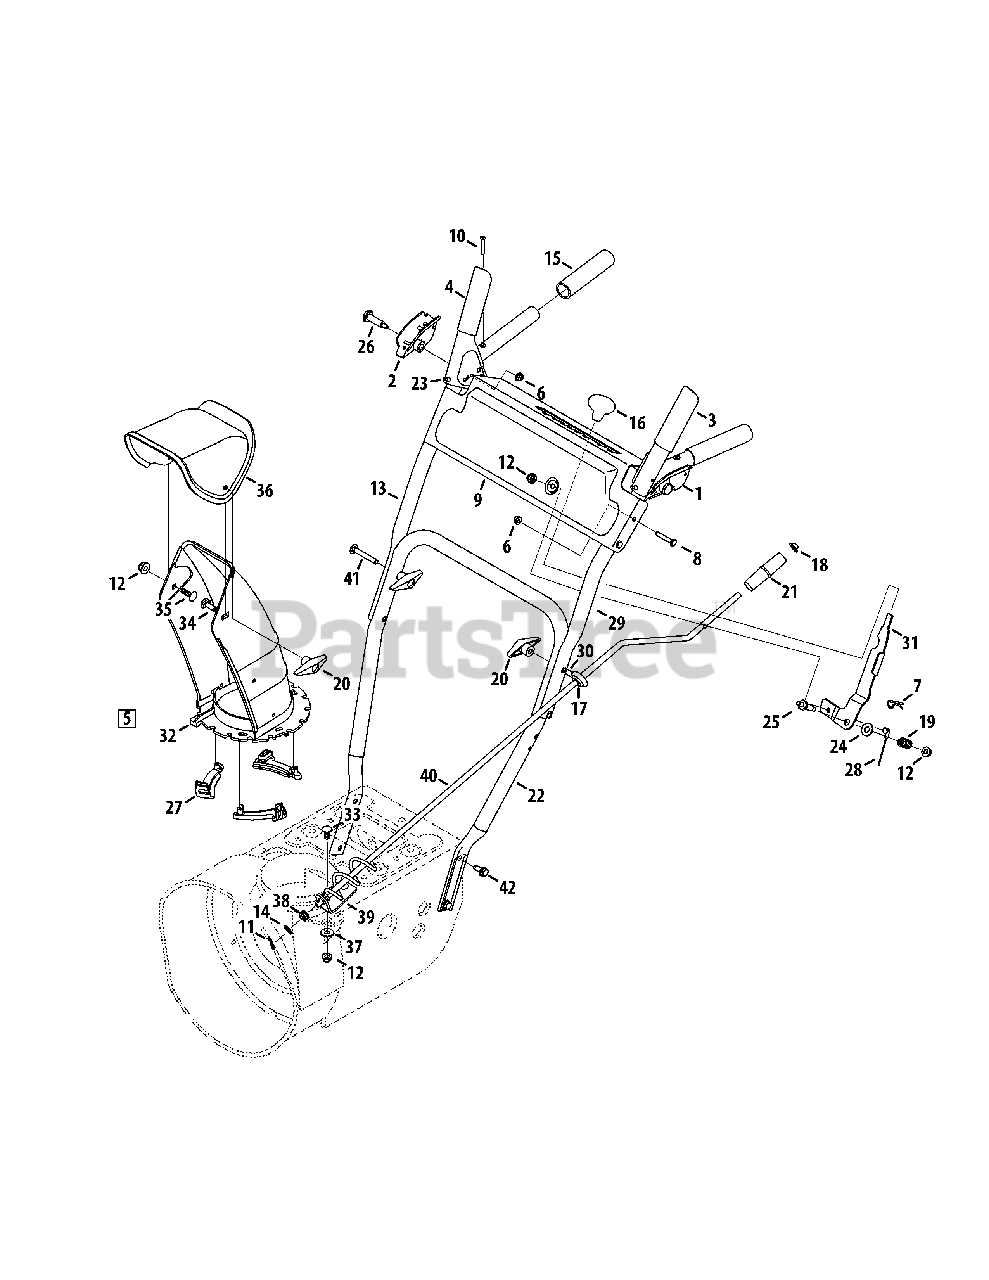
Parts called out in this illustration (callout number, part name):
1	Handle Assembly, Clutch Lock, LH
2	Handle Assembly, Clutch Lock, RH
3	Handle Ass’y, Engage, LH
4	Handle Ass’y, Engage, RH
5	Chute, Lwr (Incl. Ref. # 27, Qty. 3)
6	Nut, Flange Lock, 1/4-20
7	Click Pin
8	Screw, 1/4-20 x 1.50
9	Panel, Handle, (no cutout)
10	Screw, Machine, #10-24, 1.375
11	Pin, Cotter, .072 x 1.13
12	Nut, Flange Lock, 5/16-18, Nylon
13	Handle, Upper, RH
14	Washer, Flat, .375 x .738 x .063
15	Grip, 1.0 ID x 5.0
16	Knob, Shift, Black
17	Grommet, .44 ID x .94 OD x .50
18	Cap, Push, 3/8 Rod
19	Spring, .39 x .60 x .88
20	Knob, 5/16-18, Black
21	Crank Knob, 1.0 Dia. x 3.2, Black
22	Handle, Lower
23	Bumper, Rubber, .62 OD x .22
24	Washer, Flat, .385 x .870 x .092
25	Bolt, Shoulder, 5/16-18 x 0.905
26	Screw, Shoulder, .43 x 1.3, 1/4-20
27	Chute, Flange Keeper
28	Cable, Speed Selector
29	Handle, Upper, LH
30	Eye Bolt, Chute Crank
31	Shift Lever
32	Chute, Lower, 5.0 Dia.
33	Bolt, Carriage, 5/16-18, 1.0
34	Bolt, Carriage, 5/16-18, 1.0
35	Bolt, Carriage, 5/16-18, .750
36	Chute, Upper, w/ Label
37	Washer, .349 x .879 x .063
38	Bushing, Plastic, .380
39	Bracket, Chute Crank
40	Crank Assembly, Chute
41	Screw, Carriage, 5/16-18, 2.25
42	Screw, 5/16-18, 2.25, Gr5
